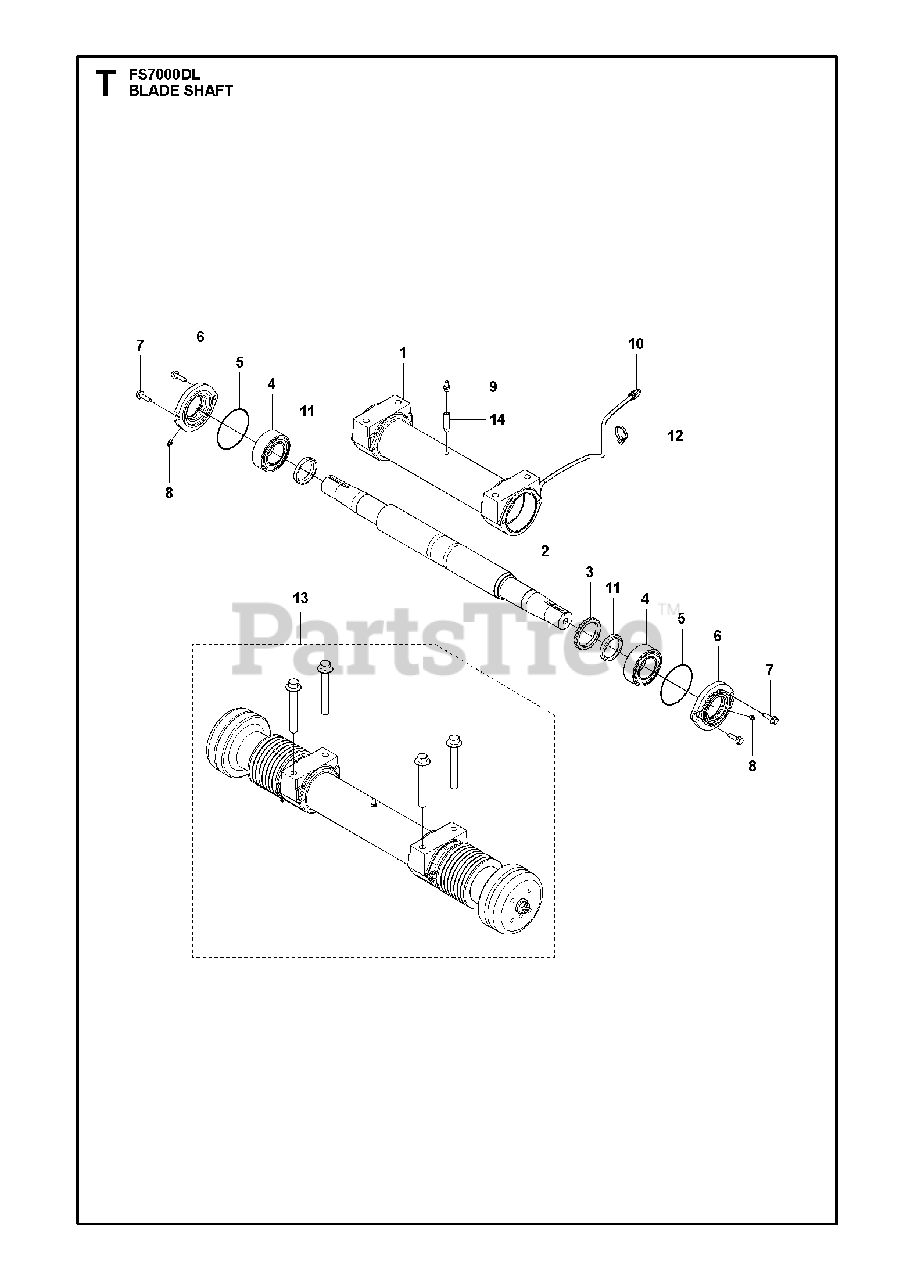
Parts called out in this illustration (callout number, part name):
13	BLADE SHAFT26” 1, 3 speed & 30” 3 speed
13	BLADE SHAFT30” 1 speed
13	BLADE SHAFT36" 3 Speed"
13	BLADE SHAFT36" 1 Speed"
13	BLADE SHAFT42" 3 Speed"
13	BLADE SHAFT42" 1 Speed"
13	BLADE SHAFT48" 3 Speed"
13	BLADE SHAFT48" 1 Speed"
